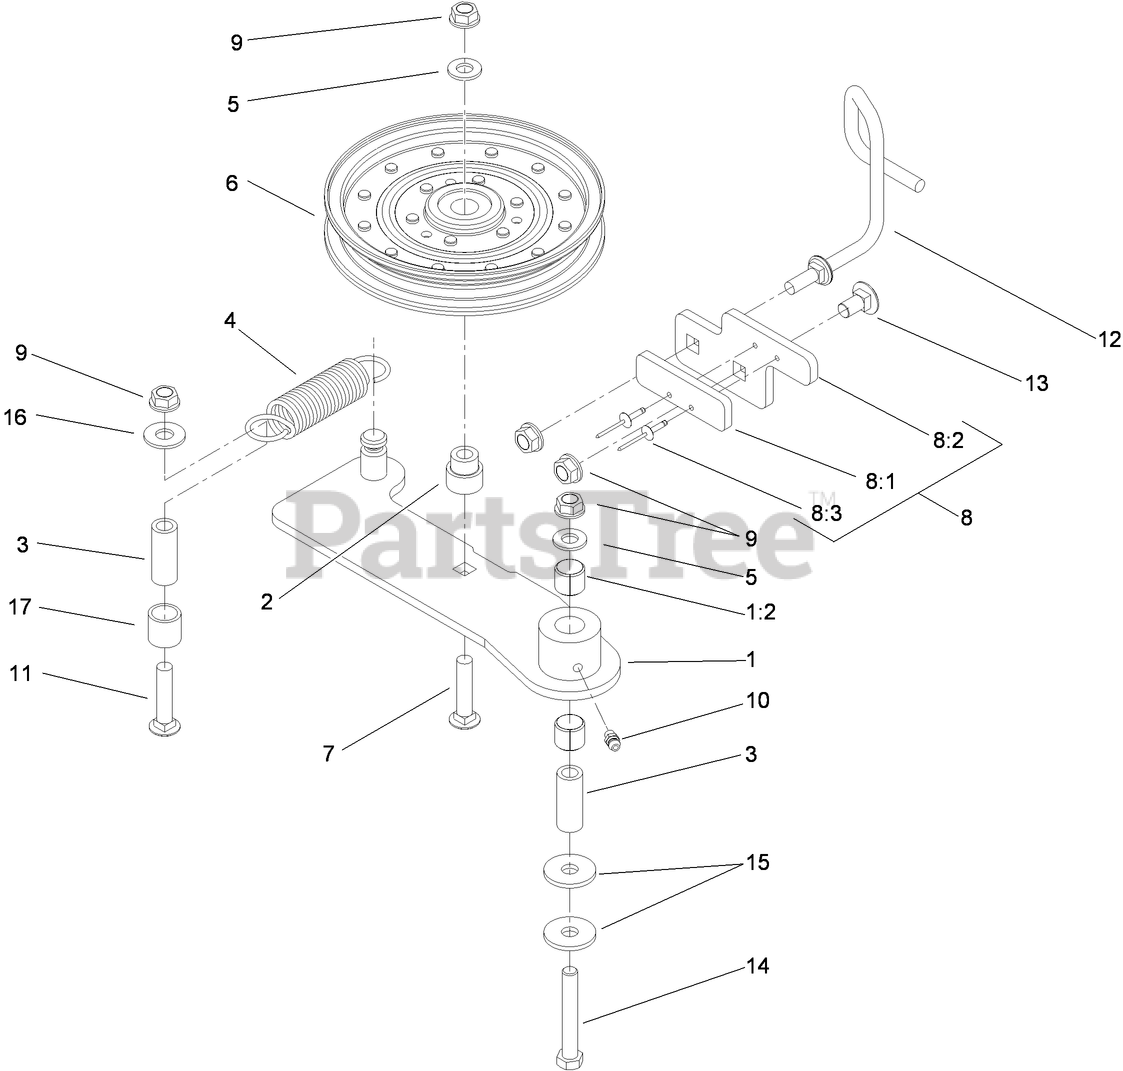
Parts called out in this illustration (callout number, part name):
1	IDLER ARM ASM
1:2	SLEEVE-BEARING
2	BUSHING-IDLER
3	BUSHING
4	SPRING-EXTENSION
5	WASHER-FLAT
6	Idler-Flat
7	SCREW-CARR
8	STOP PAD ASM
8:1	PAD-BUMPER
8:2	PLATE-STOP
8:3	RIVET
9	NUT-HHF, WHIZ
10	FITTING-GREASE
11	SCREW-CARR
12	GUIDE-BELT
13	SCREW-CARR
14	SCREW-HH
15	WASHER
16	WASHER-FLAT
17	SPACER-RUBBER
